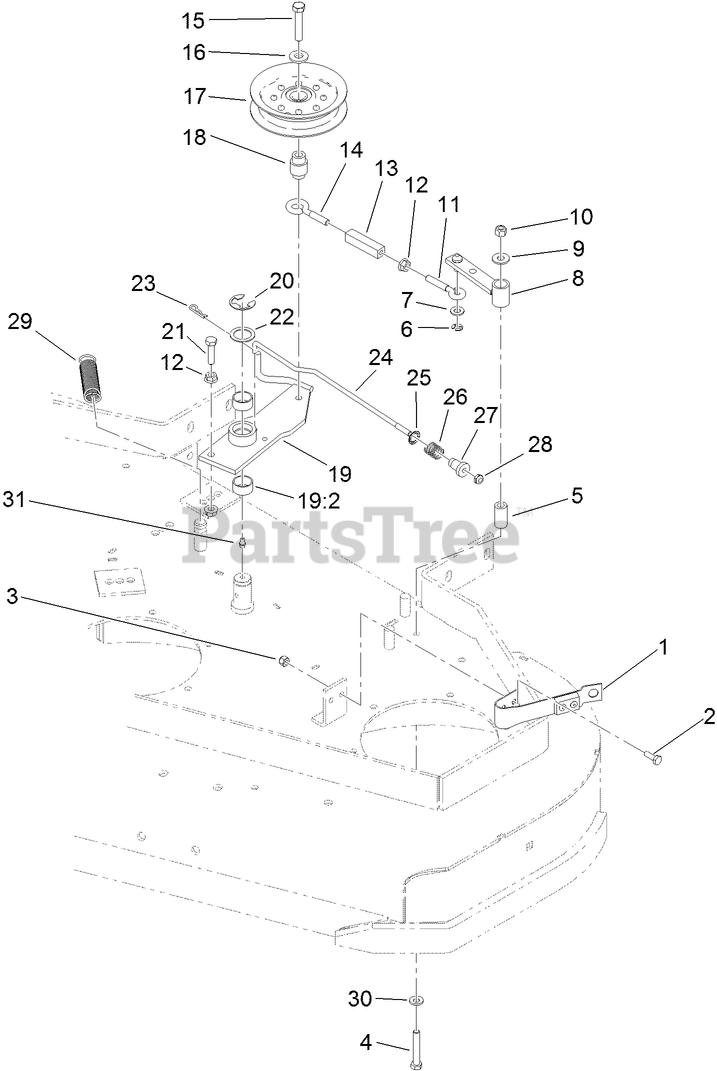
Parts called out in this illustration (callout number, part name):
1	PAD AND SPRING ASM
2	SCREW-HH
3	NUT-LOCK, NI
4	SCREW-HH
5	TUBE-PIVOT
6	RING-RETAINING, EXT
7	WASHER-PLAIN
8	ARM-ASSIST
9	WASHER-FLAT
10	NUT-LOCK, NI
11	EYEBOLT-THREAD, RH
12	NUT-HF
13	BODY-TURNBUCKLE
14	EYEBOLT-THREAD, LH
15	SCREW-HH
16	WASHER-BELLEVILLE
17	PULLEY-IDLER
18	BUSHING-ENGAGEMENT
19	Idler Arm ASM
19:2	SLEEVE-BEARING
20	RING-RETAINING, EXT
21	SCREW-HH, SPECIAL
22	WASHER-SPINDLE
23	PIN-COTTER
24	ROD-BRAKE
25	RING-PUSH ON
26	SPRING-COMPRESSION
27	SPACER-FLANGED
28	NUT-LOCK, NI
29	SPRING-EXTENSION
30	WASHER-SPRING
31	FITTING-GREASE, 90 DEG
